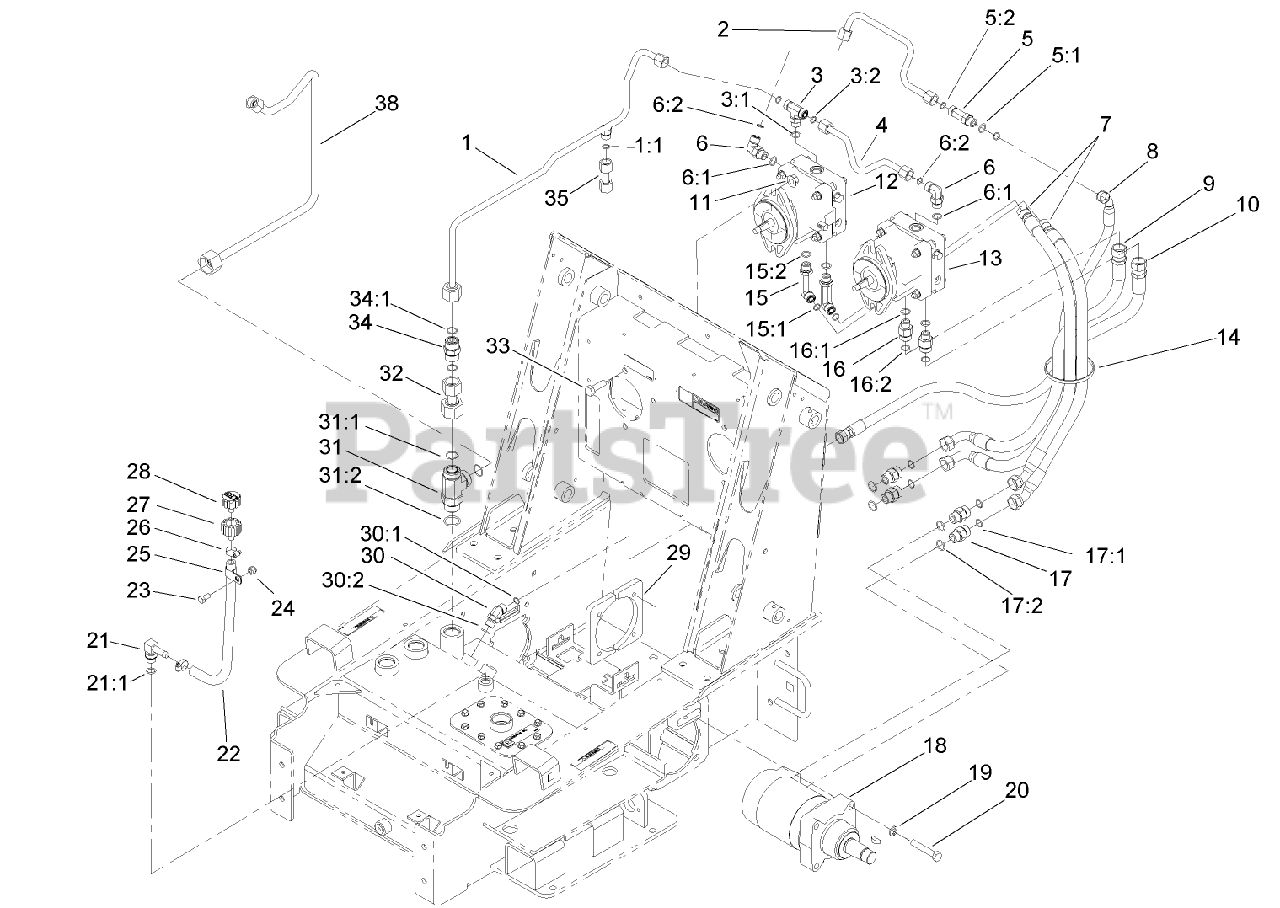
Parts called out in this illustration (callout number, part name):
1	HYD TUBE ASM
1:1	O-RING
2	TUBE-HYD
3	FITTING-HYD, TEE
3:1	O-RING
3:2	O-RING
4	TUBE-HYD
5	FITTING-TEE
5:1	O-RING
5:2	O-RING
6	FITTING-ELBOW-90 DEG
6:1	O-RING
6:2	O-RING
7	HOSE-HYD
8	HOSE-HYD
9	HYD HOSE ASM
10	HYD HOSE ASM
11	NUT-HF
12	RH HYD PUMP ASM
13	LH HYD PUMP ASM
14	TIE-CABLE
15	FITTING-ELBOW, 90 DEG
15:1	O-RING
15:2	O-RING
16	FITTING-STR
16:1	O-RING
16:2	O-RING
17	FITTING-STRAIGHT
17:1	O-RING
17:2	O-RING
18	HYD MOTOR ASM
19	WASHER-LOCK
20	SCREW-HH
21	FITTING-ELB 90
21:1	O-RING
22	HOSE-VENT
23	SCREW-HH
24	NUT-LOCK, NI
25	CLAMP-R
26	CLAMP-HOSE
27	ADAPTER-BREATHER
28	BREATHER
29	PLATE-MOUNTING
30	FITTING-HYD, 45 DEG
30:1	O-RING
30:2	O-RING
31	FITTING-TEE
31:1	O-RING
31:2	O-RING
32	TUBE-HYD
33	SCREW-HH
34	HYD CHECK VALVE ASM
34:1	O-RING
35	TUBE-HYD
38	HYD TUBE ASM
